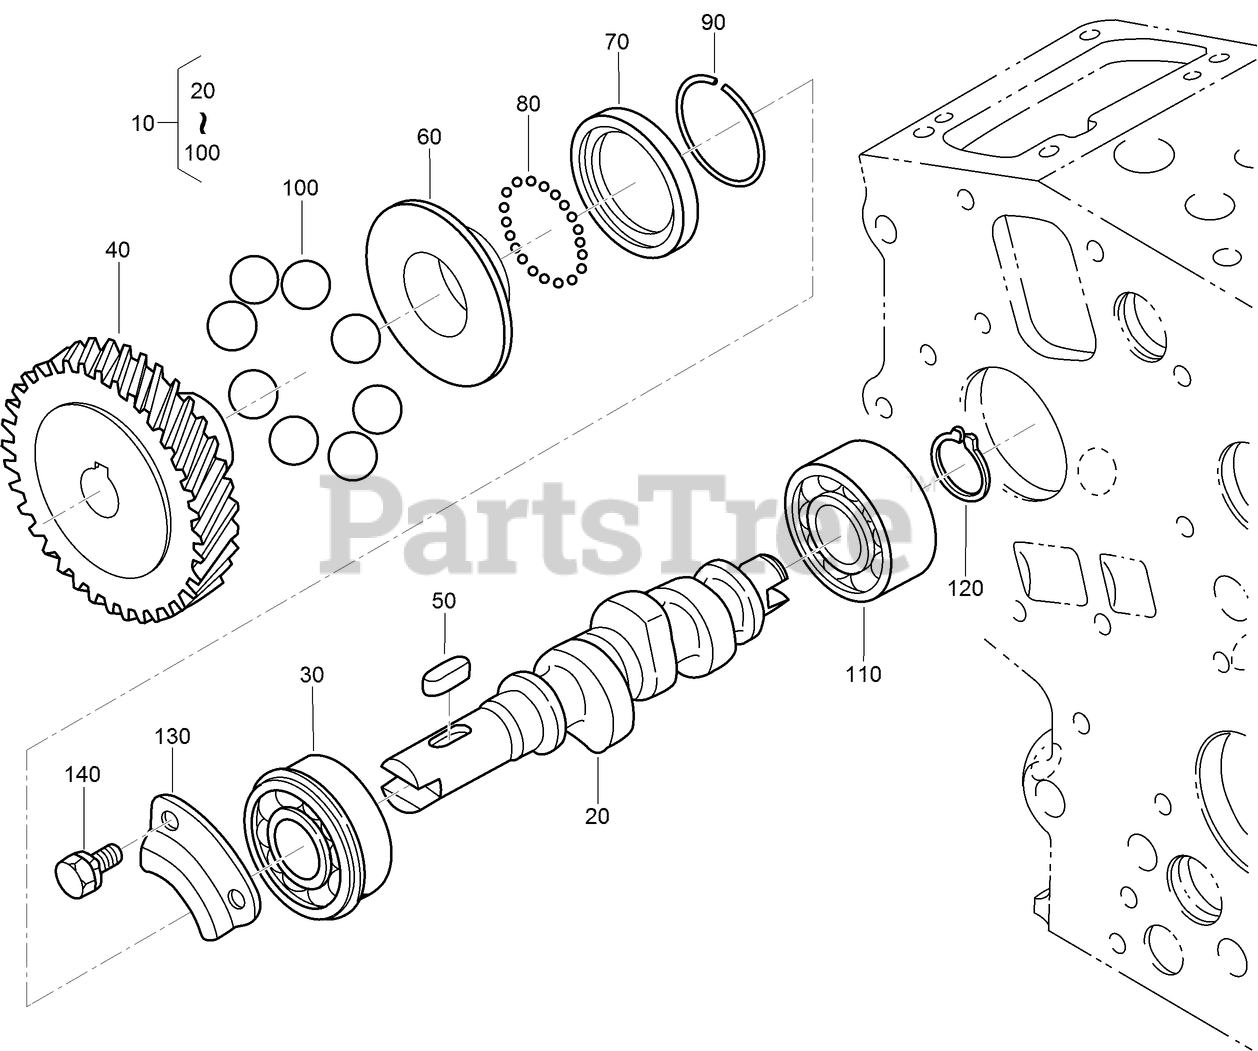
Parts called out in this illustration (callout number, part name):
10	FUEL CAMSHAFT ASM
20	CAMSHAFT-FUEL
30	BEARING-BALL
40	PUMP-GEAR, INJECTION
50	KEY-FEATHER
60	SLEEVE-GOVERNOR
70	CASE-BALL, GOVERNOR
90	CIRC-CLIP
110	BEARING-BALL
120	CIRC-CLIP, EXTERNAL
130	STOPPER-FUEL, CAMSHAFT
